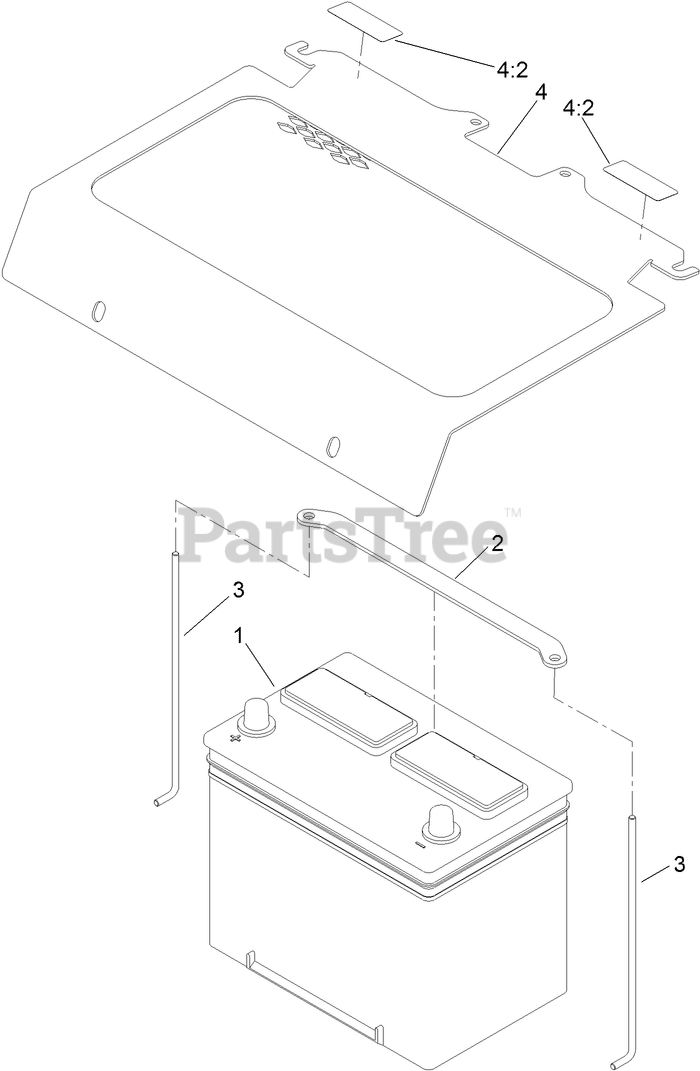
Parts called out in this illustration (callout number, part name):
1	BATTERY
2	STRAP-HOLD DOWN, BATTERY
3	ROD-HOLD DOWN, BATTERY
4	FRONT COVER ASM
4:2	DECAL-SURFACE, HOT
